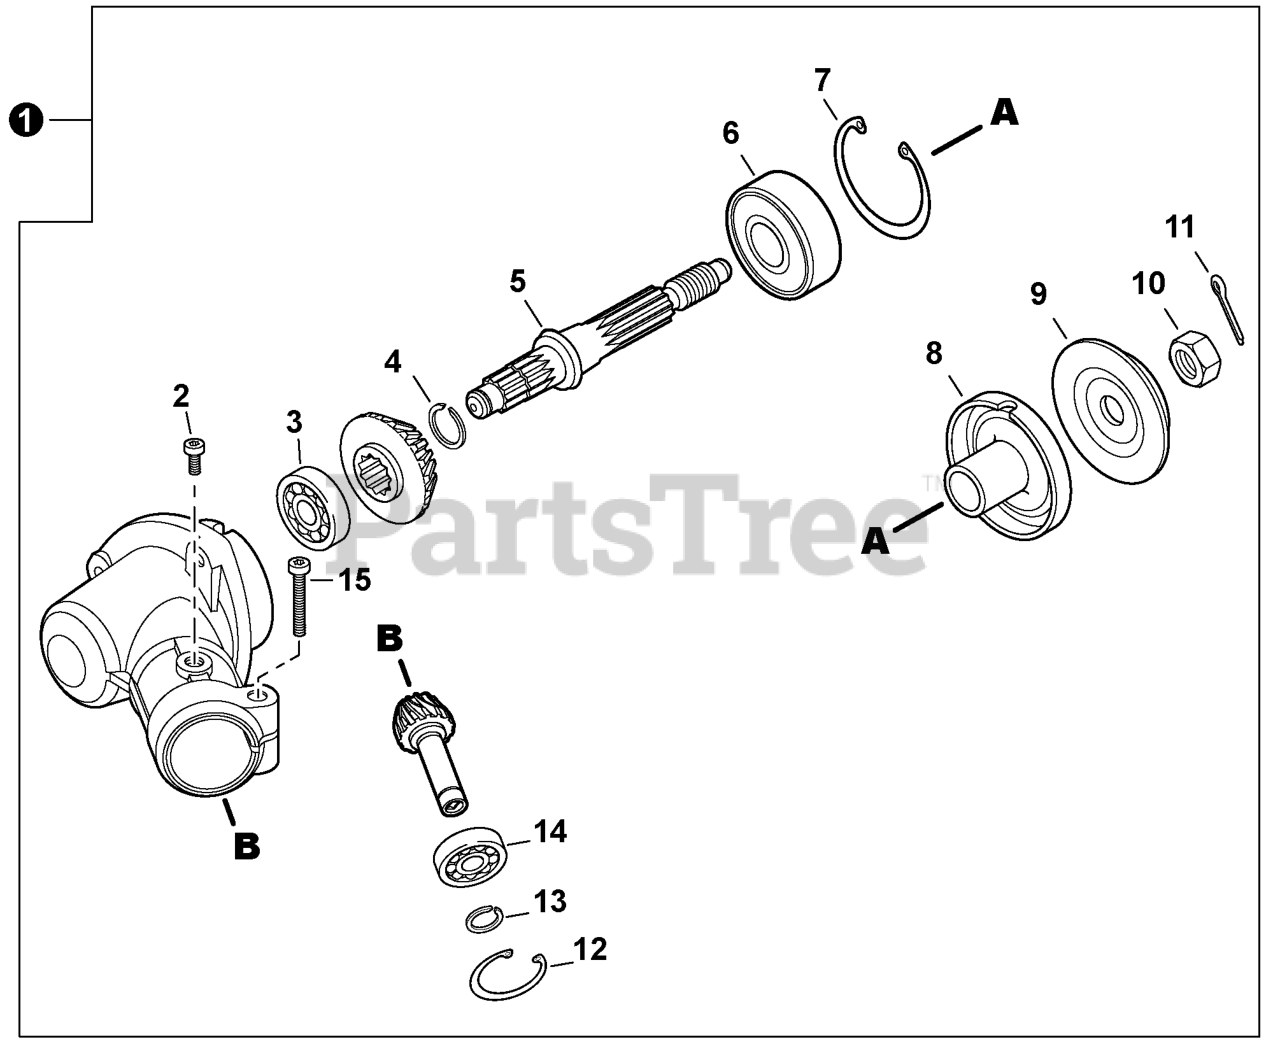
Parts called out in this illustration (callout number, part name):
1	GEAR CASE ASSY
2	BOLT, TORX 5x12
3	BEARING, BALL 609A
4	RING, SNAP 12
5	SHAFT, GEAR
6	BEARING, BALL 6201 2RS
7	RING, SNAP 32
8	PLATE, ADAPTOR - UPPER
9	PLATE, ADAPTOR - LOWER
10	NUT 10x1.25 LH
11	PIN, COTTER 2x22
12	RING, SNAP 24
13	RING, SNAP 9
14	BEARING, BALL 609ZA
15	BOLT, TORX 5x25
